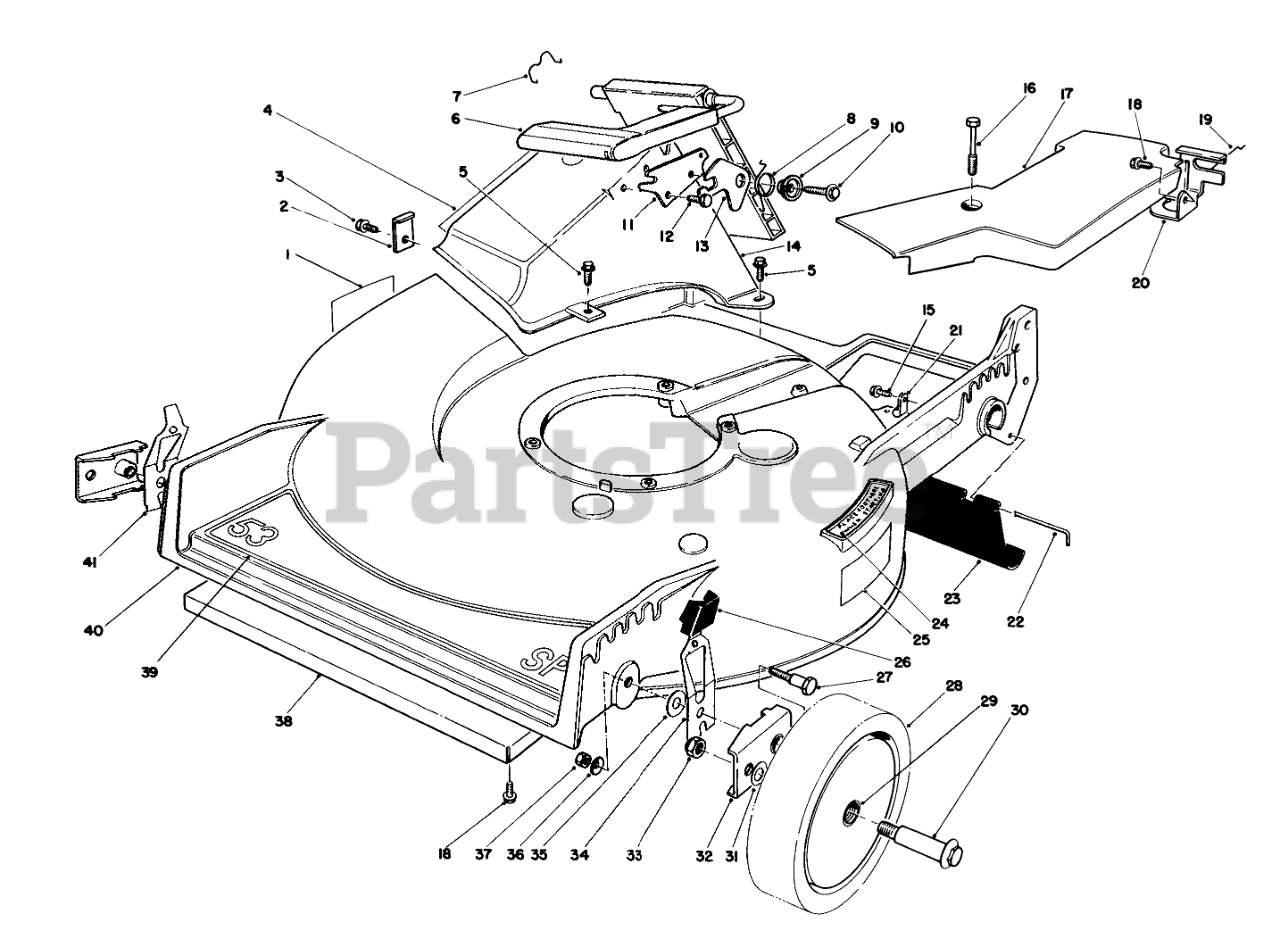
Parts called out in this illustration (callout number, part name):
1	Decal Danger
2	TUNNEL CLIP
3	SCREW
4	DECAL - DANGER
5	SCREW-HWH
6	Discharge Door Assembly
7	DOOR RET SPRING
8	TORSION SPRING
9	DOOR SPACER
10	SCREW-HWH
11	DOOR LATCH PLATE
12	SCREW-PLASTITE
13	SAFETY LATCH
14	Tunnel Discharge
15	SCREW
16	SCREW-HHFTF
17	Belt Cover
18	SCREW-HWHTF
19	RETAINER-CABLE
20	Bracket-Traction Adj.
21	CLAMP-CABLE
22	ROD-SHIELD
23	SHIELD-TRAILING
24	DECAL - STEP PAD INT'L
25	Decal Danger
26	KNOB-ARM
27	PIVOT SCREW
28	Wheel & Tire Assembly (Incl. Ref. #29)
29	BUSHING
30	BOLT-WHEEL
31	WASHER
32	HP PIVOT ARM ASM
33	Nut
34	L. HP SPRING ARM ASM
35	WASHER-PIVOT
36	WASHER-BELLEVILLE
37	NUT-LOCK, NI
38	Shield-front
39	DECAL - 53 SP DECK
40	21" Housing
41	R HP SPRING ARM ASM
